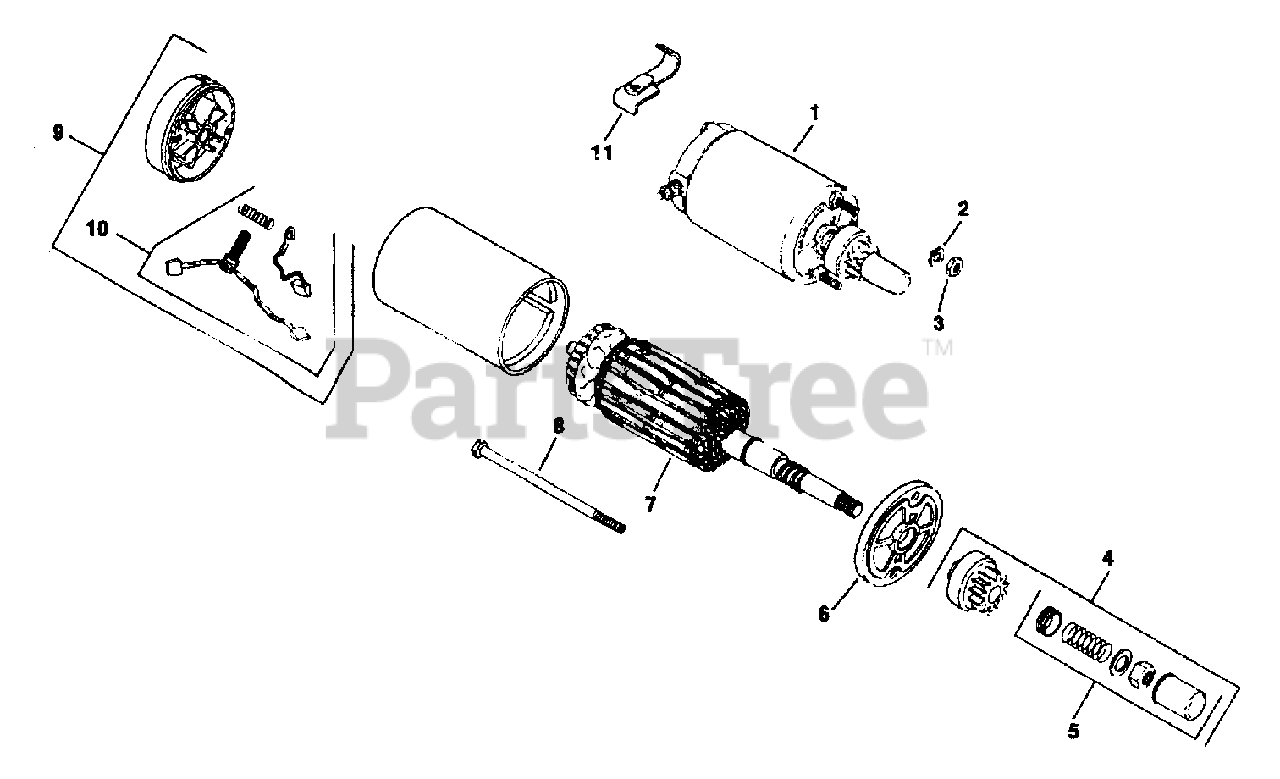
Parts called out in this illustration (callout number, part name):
1	STARTER ASSEMBLY
2	WASHER
3	NUT
4	KIT
5	KIT
6	CAP
7	ARMATURE
8	BOLT
9	CAP
10	KIT, BRUSH
11	BRACKET, MOUNTING
